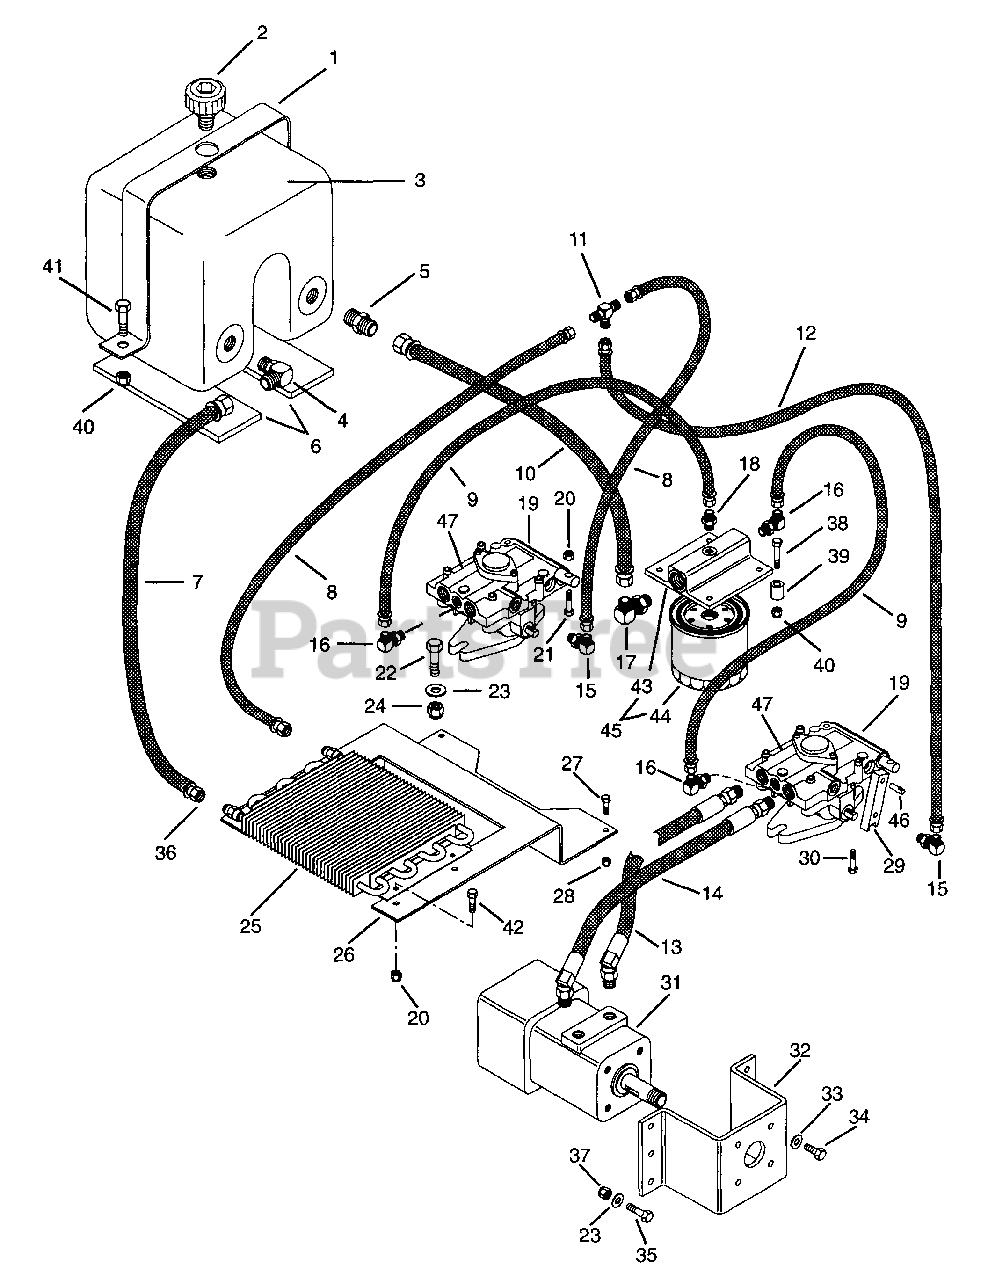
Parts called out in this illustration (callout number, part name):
1	Strap, Tank
2	Cap, Filter
3	Tank, Hydraulic
4	Adapter .37 - .875
5	Adapter, Hydraulic
6	Pad, Gas Tank
7	Hose, Hydraulic Cooler to Tank
8	Hose, Hydraulic Valve to Tank
9	Hose, Oil Filter to Pump
10	Hose, Hydraulic Tank to Filter
11	Adapter-Tee .56-18
12	Hose, Pump to Tee
13	Assembly,, Hose Wheel Motor to Pump
14	Assembly, Hose Wheel Motor to Pump
15	Adapter 2503-6-6
16	Adapter 2503-4-4
17	Adapter-Pipe .75-16
18	Adapter 0503-4-4
19	Variable Displace Pump
20	Nut-Locking-Nylon .250-20 Grade 2
21	Bolt-Hex .25-20 x 2.00 Grade 5
22	Bolt-Hex .38-16 x 1.125
23	Washer-Flat-Steel .406 x .812 x .065
24	Nut-Locking-Center .625-10 Grade 2
25	Cooler, Oil
26	Bracket, Oil Cooler
27	Bolt-Hex .38-16 x 1.125
28	Nut-Locking-Nylon .375-16 Grade 2
29	Arm, Pump Actuating
30	Screw-Cap 10-24 x .75
31	Motor, Hydraulic Wheel
32	Bracket, Wheel Motor
33	Washer-Lock .375 x .094
34	Bolt-Hex .380-16 x .875
35	Bolt-Hex .375-16 x 1.00 Grade 5
36	Clamp, .88 Diameter Hose
37	Nut-Locking-Nylon .375-16 Grade 2
38	Bolt-Hex .31-18 x 2.00 Grade 5
39	Bushing, Sleeve .328 x .462 x 1.00
40	Nut-Locking-Nylon .312-18 Grade 2
41	Bolt-Hex .31-18 x .75 Grade 5
42	Bolt-Hex .25-20 x .63
43	Assembly, Head
44	Element
45	Assembly, Spin-On Lube
46	Pin-Dowel .312 x 1.25
47	Kit-Seal
